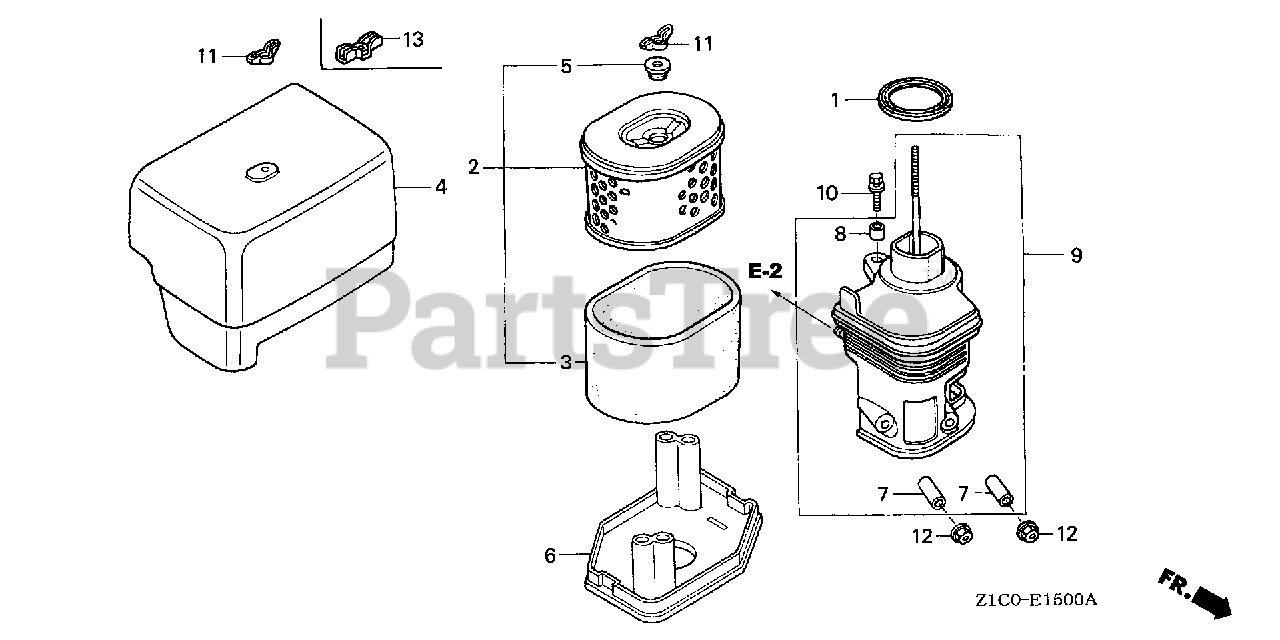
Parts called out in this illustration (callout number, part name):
1	GASKET, ELBOW
2	ELEMENT, AIR CLEANER
3	FILTER (OUTER)
4	COVER, AIR CLEANER
5	GROMMET, AIR CLEANER
6	NOSE, MUFFLER
7	COLLAR, AIR CLEANER
8	COLLAR B, AIR CLEANER
9	ELBOW, AIR CLEANER
10	BOLT-WASHER (6X22)
11	WINGNUT, TOOL BOX SETTING
12	NUT, FLANGE (6MM)
13	WINGNUT (6MM)
